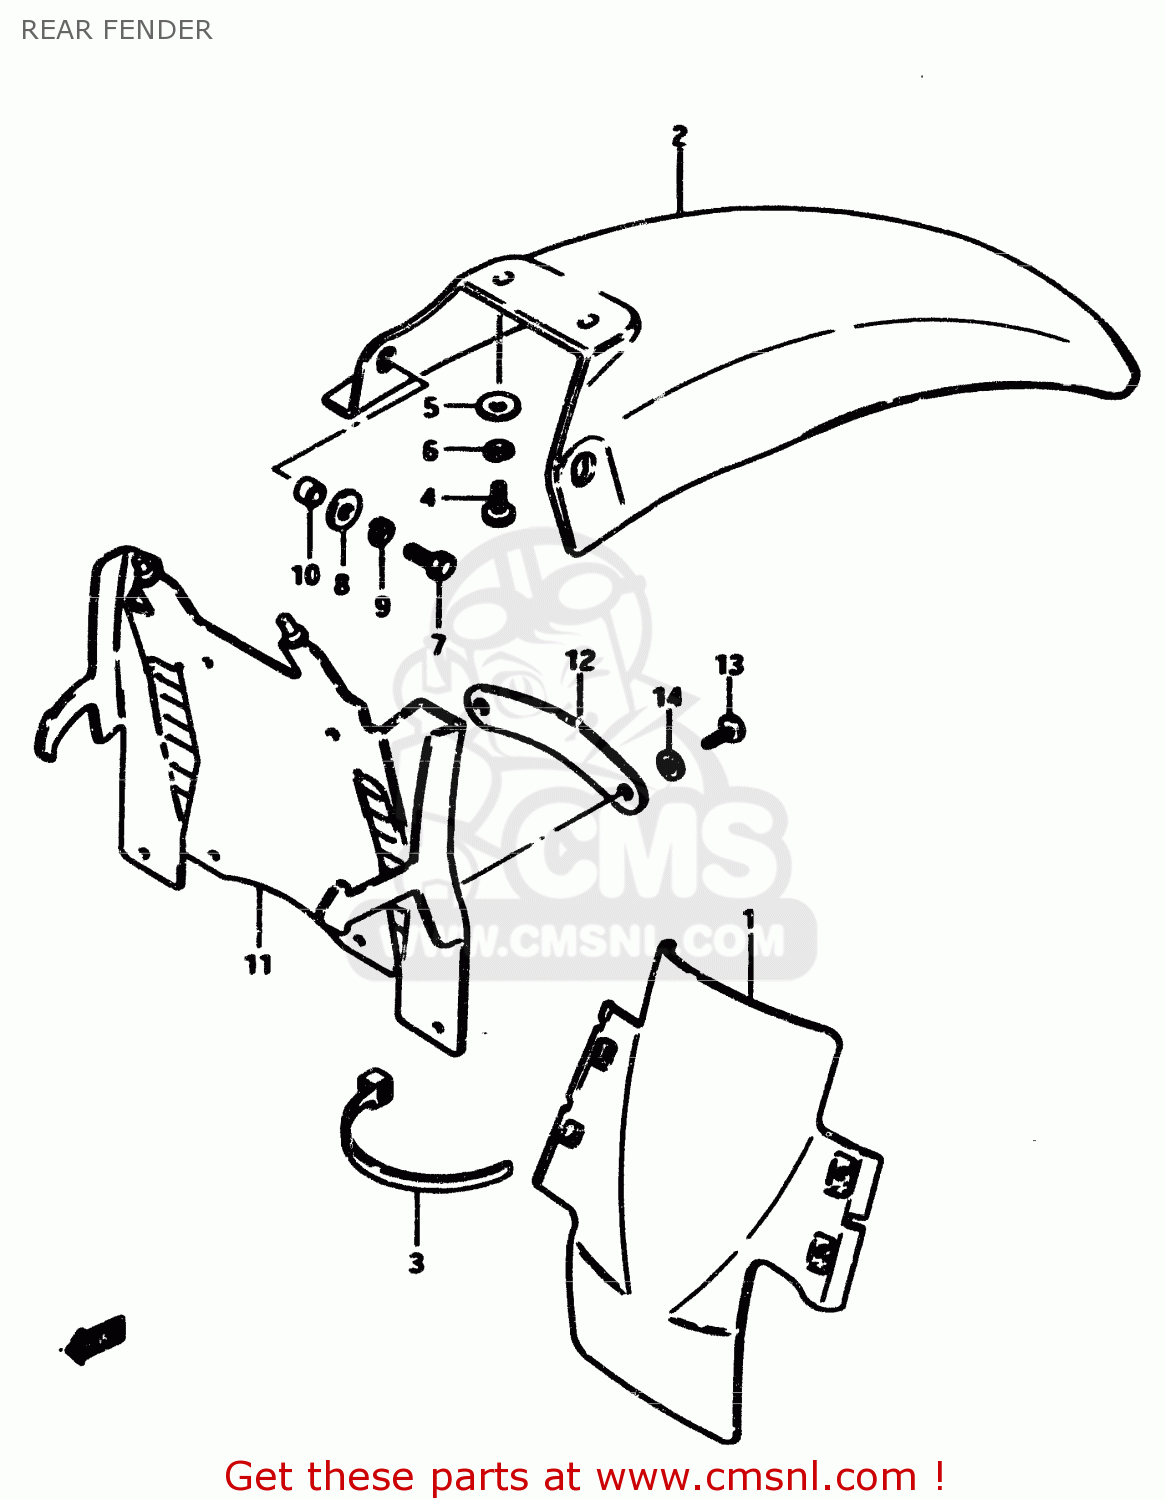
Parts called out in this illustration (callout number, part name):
1	REAR FENDER,FRONT
2	FENDER,REAR
3	CLAMP
4	SCREW
5	WASHER
6	WASHER,LOCK
7	BOLT, UPPER
8	WASHER (6.5X20X1.2)
9	WASHER,LOCK
10	SPACER
11	MUD GUARD,REAR FENDER
12	PLATE,MUD GUARD
13	SCREW
14	WASHER,5MM
